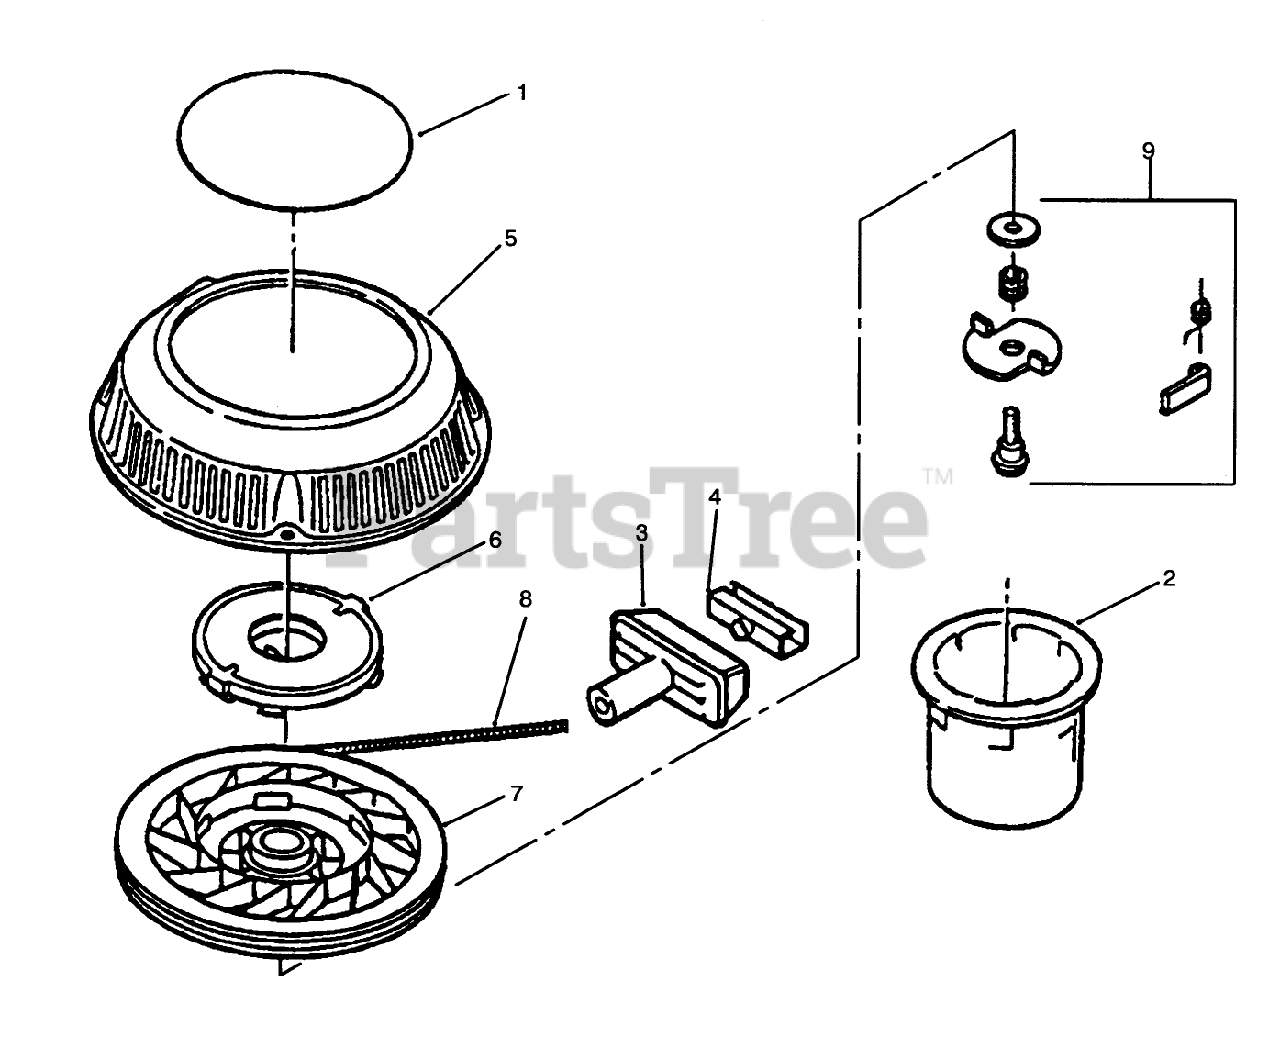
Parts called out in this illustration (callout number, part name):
2	HUB STARTER SM
4	CLIP-STARTER
5	STARTER HOUSING & SHAFT
6	SPRING KEEPER ASM
9	DOG KIT
